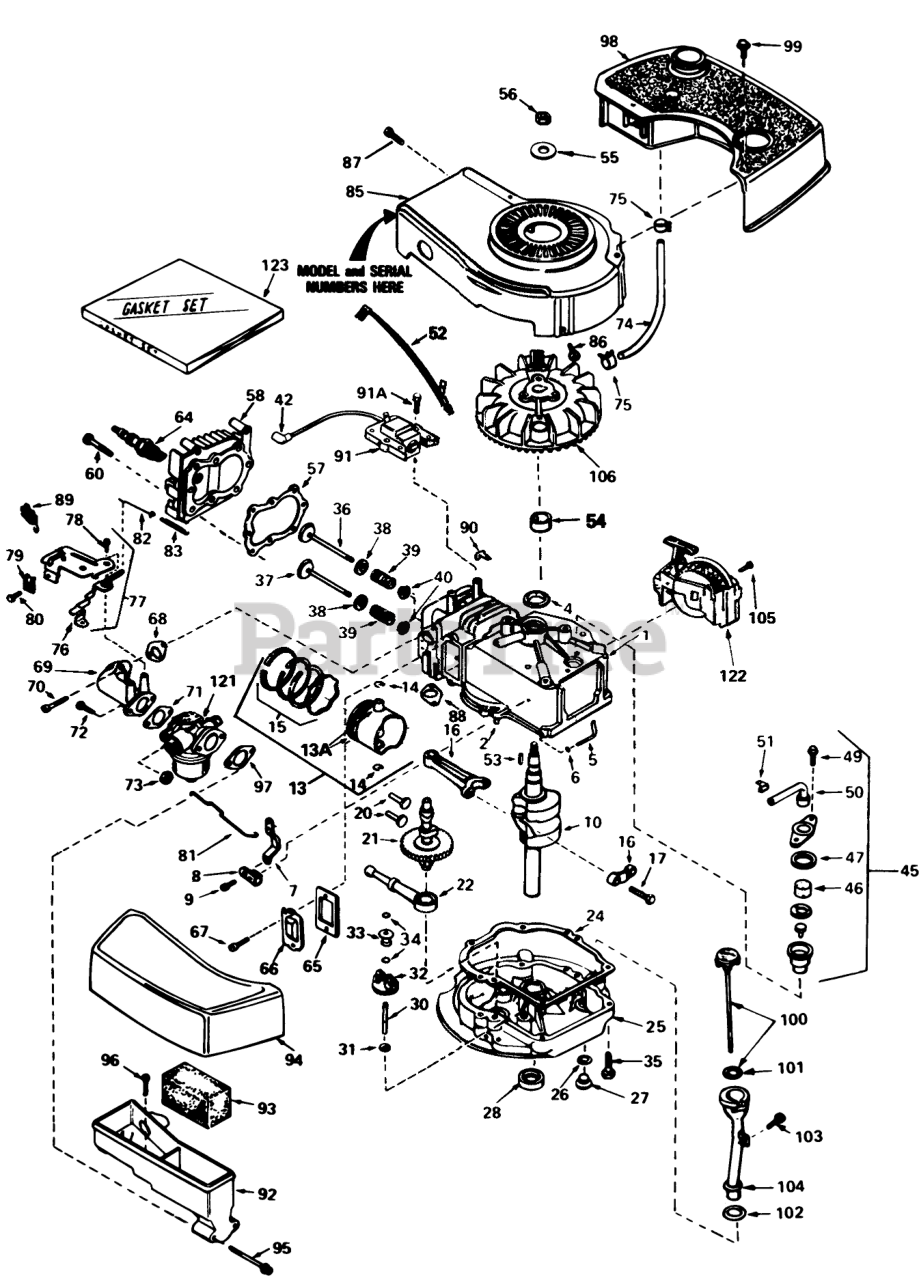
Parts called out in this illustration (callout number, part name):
1	Cylinder Assy. (Incl. #2 & 4)
2	Pin-Dowel
4	Seal-Oil
5	Rod, Governor (Incl. #6)
6	Washer-Flat
7	Governor Lever
8	Clamp-Lever, Governor
9	Screw
10	Crankshaft
13	Piston, Pin & Ring Assy. (Std.)(Incl. #13A, 14 & 15)
13	Piston, Pin & Ring Assy.(.010 oversize)(Incl. #13A, 14 & 15)
13	Piston, Pin & Ring Assy.(.020 oversize)(Incl. #13A, 14 & 15)
13A	Piston & Pin Assy. (Std.)(Incl. #14)
13A	Piston & Pin Assy. (.010 oversize)(Incl. #14)
13A	Piston & Pin Assy. (.020 oversize)(Incl. #14)
14	Ring-Retaining, Piston Pin
15	Ring Set (Std.)
15	Ring Set (.020" OS)
15	Ring Set (.010" OS)
16	Rod Assy., Connecting (Incl. #17)
17	Bolt-Rod, Connecting
20	Lifter-Valve
21	Camshaft(Mech.Comp. Release)
22	Oil Pump ASM
24	Gasket, Mounting
25	Flange Assy., Mounting (Incl. #26 thru 30)
26	Gasket-Oil Drain
27	Plug Oil Drain
28	Seal Oil
30	Shaft-Governor
31	Washer-Flat
32	Gear Assy., Governor (Incl. #31)
33	Spool-Governor
34	Ring-Retaining
35	Screw (1/4-20 x 1-1/4)
36	Valve, Intake (Std.)(Incl. #40)
36	Valve, Intake (1/32" oversize)(Incl. #40)
37	Valve, Exhaust (Std.)(Incl. #40
37	Valve, Exhaust (1/32" oversize)(Incl. #40)
38	Cap-Upper Valve Spring
39	Spring-Valve
40	Cap-Valve, Spring
42	Cover-Spark Plug
45	Breather Assy. (Incl. #46 thru 51)
46	Element-Breather
47	Gasket-Breather
49	Screw (10-24 x 9/16)
50	Tube, Breaker
51	Clip, Breather
52	Wire-Ground
53	Key-Flywheel
55	Washer-Belleville
56	Nut-Flywheel
57	63573 GIL 42 SNWTHW
58	Head-Cylinder
60	Screw (5/16-18x1-1/2)
64	Plug, Spark (J17LM or equiv.)
64	Plug, Spark (Champion RCJ-8)
65	Gasket-Breather
66	Cover-Valve
68	Gasket-Intake
69	Pipe, Intake (Incl. #68)
70	Screw (1/4-20 x 1)
71	Gasket-Carburetor
72	Screw (1/4-28 x 7/8)
73	Nut and Lock Washer (1/4-28)
74	Line-Fuel
75	Clamp-Line, Fuel
76	Lever Control
77	Control Assy., Speed (Incl. #76, 78 & 89)
78	Screw, Hex Washer Hd Shoulder Self-Tap
79	Conduit
80	Screw (10-32 x 3/8)
81	Link-Throttle
82	Link Governor Spring
83	Spring Governor
85	Housing-Blower
86	Screw (1/4-20x19/32)
87	Screw (10-24 x 9/16)
88	Gasket Exhaust
89	Terminal
90	Clip-Wire
91	Lamination & Coil Assy. (Solid State)(Incl. #42)
91A	Screw
92	Body Air Cleaner
93	Filer, Air
94	Cove, Air Cleaner
95	Screw Fil Hd.
96	Screw, Hex Hd.
97	Gasket-Air Cleaner
98	Tank-Fuel
99	Screw (10-32 x 35/64)
100	Dipstick, Oil (Incl. #101)
103	Screw (10-32 x 1/2)
104	Tube-Oil Fill
105	Screw (1/2-20x5/8)
106	Flywheel
121	Carburetor (Incl. #71)
122	Starter-Sidemount
123	Gasket Set
